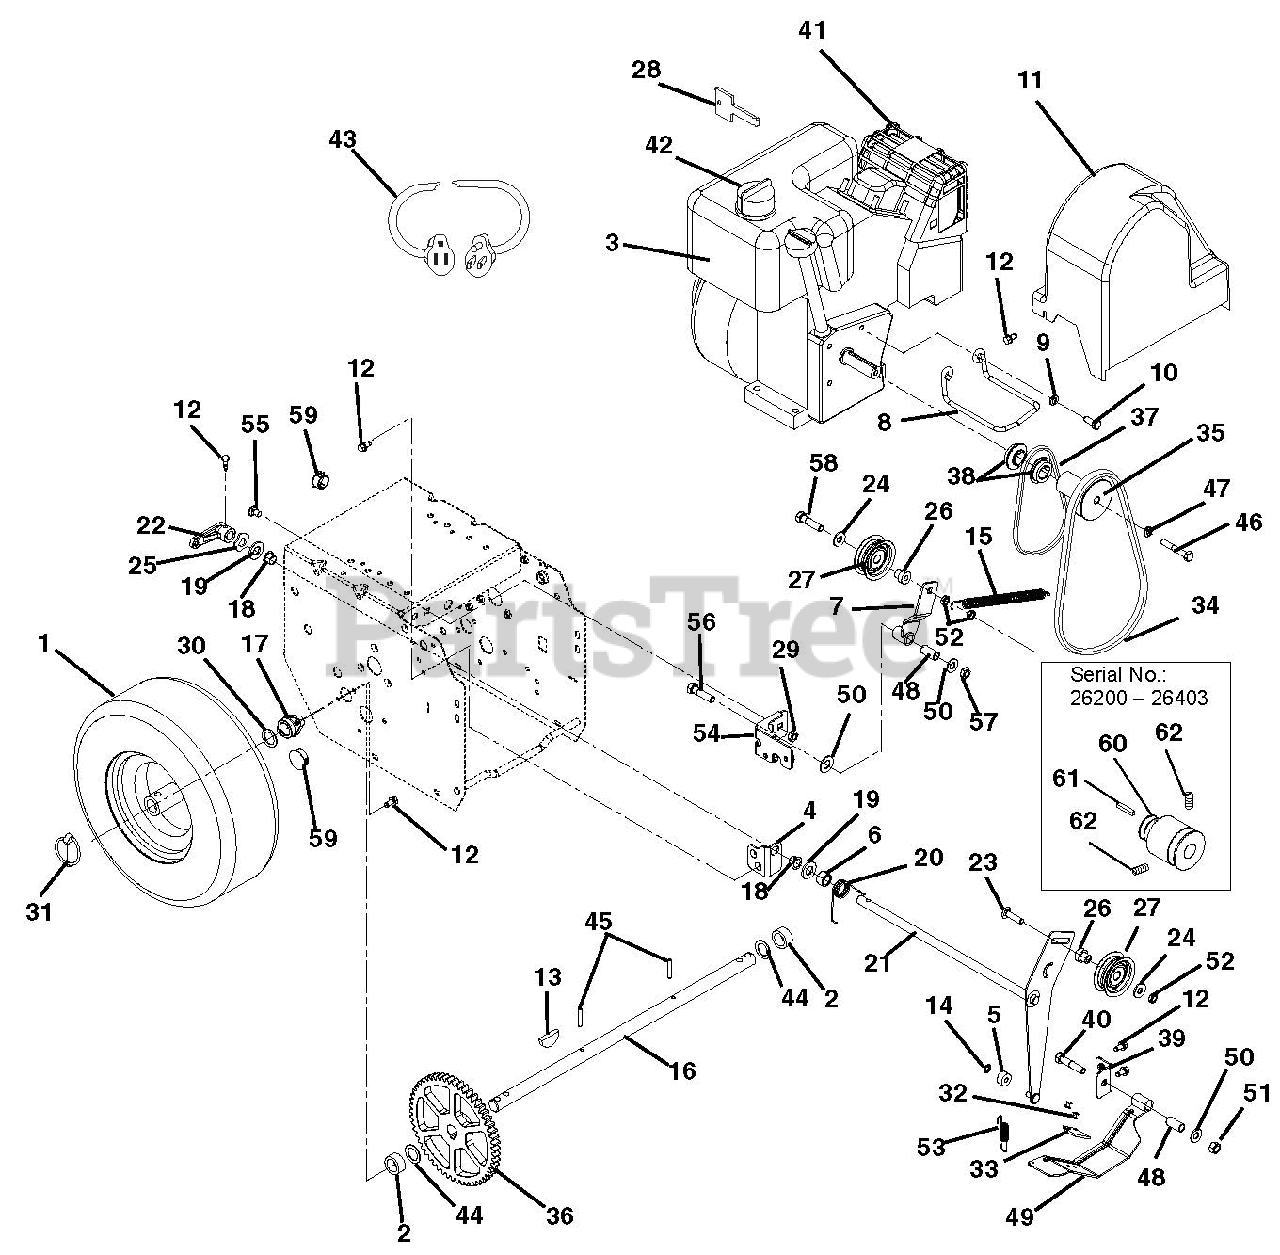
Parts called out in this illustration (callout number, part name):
1	TIRE/WHEEL, RH 4.10-6 PIN K478
1	TIRE/WHEEL, LH 4.10-6 PIN K478
1	TIRE, 4.10-6 K478
2	BSHG-SLV .766 X 1.125 X .500
3	ENGINE, 6HP TEC OHV 120V
3	ENGINE, 7HP TEC OH195SA 120V
4	BRACKET, MOUNT - IDLER ARM
5	BSHG,SLV .270 X .750 X .250
6	BSHG-SLV .510X.751X.475
7	WELDMENT, TRACTION IDLER ARM
8	FINGER, BELT
9	WSHR-LK .312X.097 HVY YWZC
10	BLT-HEX .31-24X.75 YWZC GR5
11	PLZ SEE SERVICE LETTER #L-2166
12	@SCR-TAP .25-20X.50 HWH TR YWZ
13	KEY-WDRF .25X.750X.313 SAE91
14	RG-RTNG-EXT .250X.010
15	SG-TENS .062X.56X8.0 WLD 11
16	SHAFT, AXLE
17	BSHG .75X1.125X.65
18	BUSHING, POLYLINER-.50 SPLIT
19	@WSHR-FL-STL.531X1.06X.095YWZC
20	SG-TORS .075 X .955
21	WELDMENT, ATTACHMENT IDLER ARM
22	ARM, CLUTCH - ATTACHMENT
23	@BLT-RHDSHSQNK.31-18X1.25 G5YZ
24	@WSHR-FL-STL.38X.875X.083 YWZC
25	WSHR-WAVE .50X.75X.015 .13FRHT
26	SPCR, BRG .315X.50X.688X.281
27	IDLER
28	KEY, PUSH/PULL - TECUMSEH
29	@NUT-LK-TOP-FLG .31-18 YWZC
30	WSHR-FL-STL.754X1.125X.062YWZC
31	PIN-LOK .31X1.75
32	RVT-POP .187 YZ
33	PAD, BRAKE
34	V-BELT, 4L-RAW EDGE
35	SHEAVE, ATTACHMENT DRIVE
36	SPUR GEAR, 54T .75ID X 6.75PD
37	V-BELT, 3L-WRAPPED
38	TRACTION SHEAVE HALF
39	BRACKET, MOUNT - BRAKE
40	@BLT-HEX .38-16X1.75 GR5 YWZC
41	PLUG, SPARK
42	CAP, FUEL - TECUMSEH
43	CORD, ELECTRIC START CORD 120V
44	WSHR-FL-STL.754X1.125X.062YWZC
45	PIN-ROLL .188X1.25
46	BLT-HEX .31-24X2.00 GR5
47	WSHR-LK .312X.097 HVY YWZC
48	BSHG-SLV .385X.500X1.045
49	BRAKE ARM W/PAD
50	@WSHR-FL-STL.406X.812X.065 YWZ
51	@NUT-LK-CTR .38-16 YWZC
52	@NUT-LK-CTR-JAM .31-18 YWZC
53	SPRING-EXT .437 X .438 X 2.64
54	WELDMENT, FRAME BRACKET
55	@BLT-RHDSSQNK .31-18X.62 G5YZ
56	@BLT-HEX .38-16X1.50 GR5 YWZC
57	@NUT-LK-CTR-JAM .375-16 YWZC
58	@BLT-HEX .31-18X1.50 GR5 YWZC
59	PLUG, HOLE - 1.00" NYLON
60	ENGINE SHEAVE, ONE-PIECE
61	KEY-SQ .188X1.0X.188 SAE 8630
62	SCR-SET .31-18X.38 SKHCUPDL
